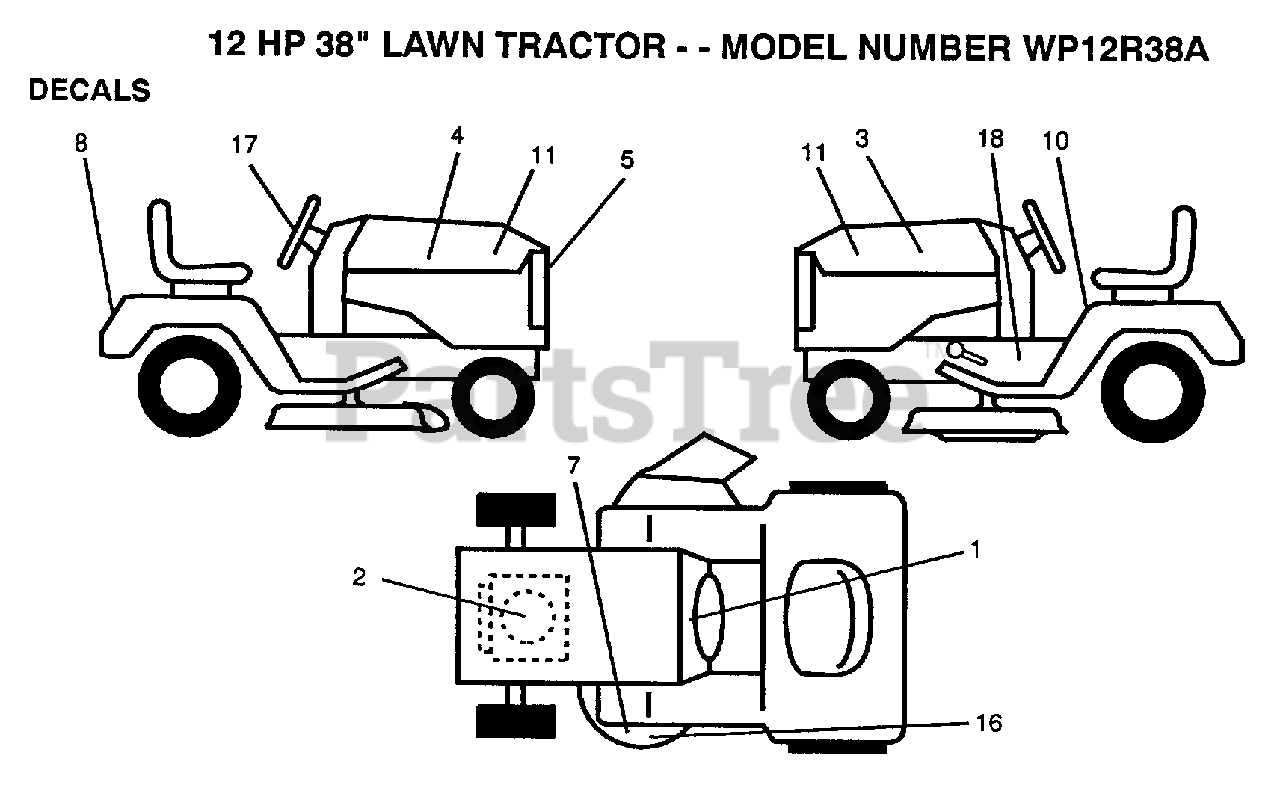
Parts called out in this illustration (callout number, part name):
2	DECAL.ENG.271967
5	"DECAL,LIGHT BOX"
7	DECAL INSTRUCTION CAUTION
8	DECAL, FENDER LOGO
10	DECAL
11	DECAL.HOOD.LOGO.
16	"DECAL,ENVIRO DECK"
17	DECAL, WHEEL CAP
18	IND HGT DECK DECA
